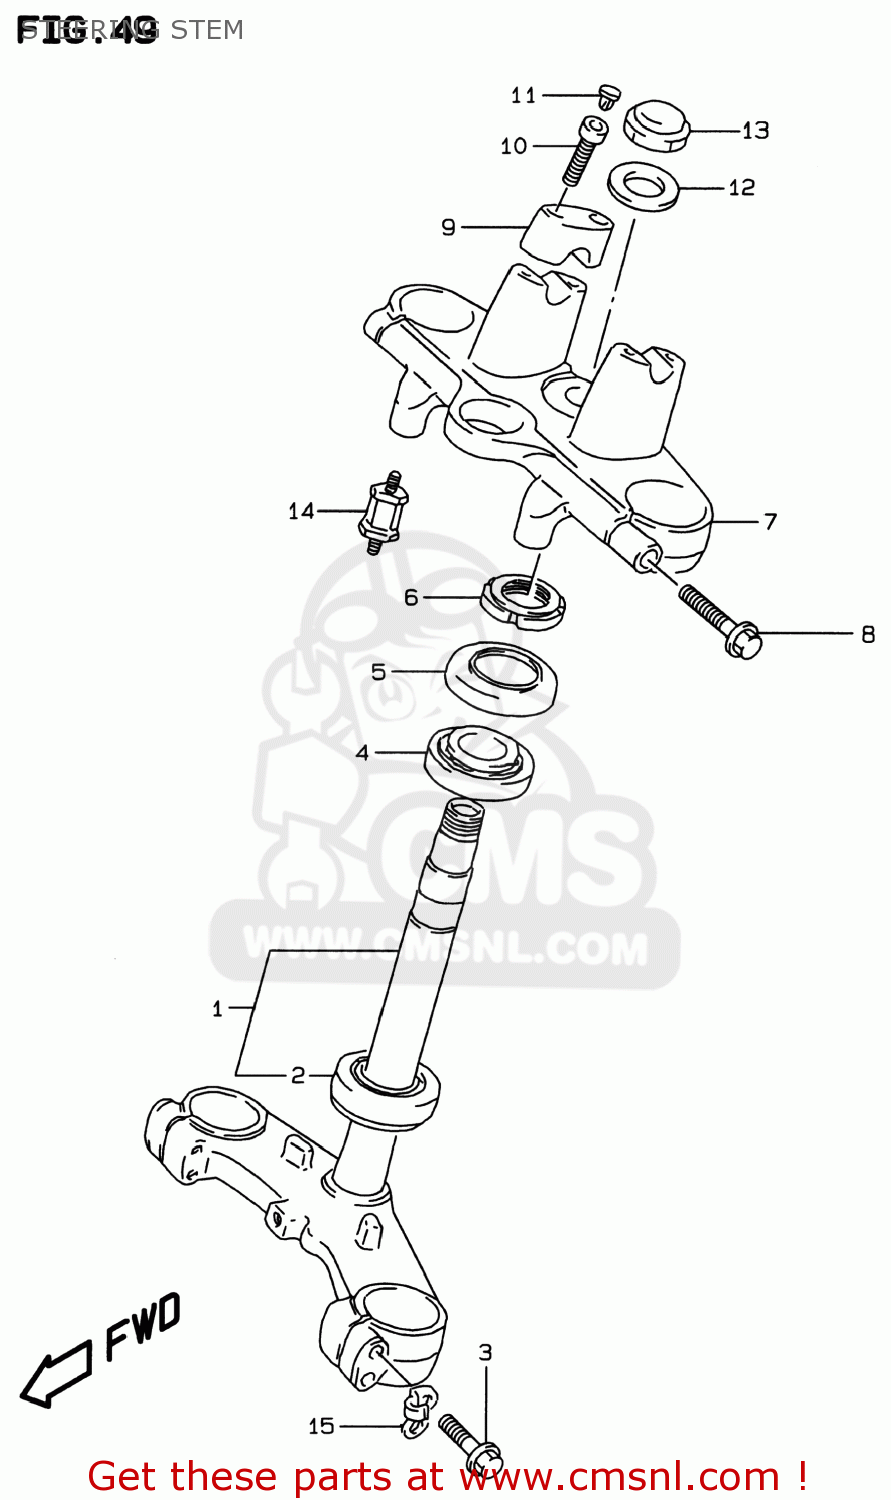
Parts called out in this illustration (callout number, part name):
1	STEM,STEERING
2	BEARING(30X55X17)
3	BOLT
4	BEARING(25X47X15)
5	SEAL,STEERING UPR DUST
6	NUT,STEERING STEM(25X44X10)
7	HEAD,STEERING STEM
8	BOLT
9	HOLDER,HANDLE UPR
10	BOLT
11	CAP(OD:11)
12	WASHER(22.5X35.9X1.6)
13	NUT,CAP
14	BOLT,SPEEDOMETER CUSHION
15	GUIDE,SPEEDOMETER CABLE
